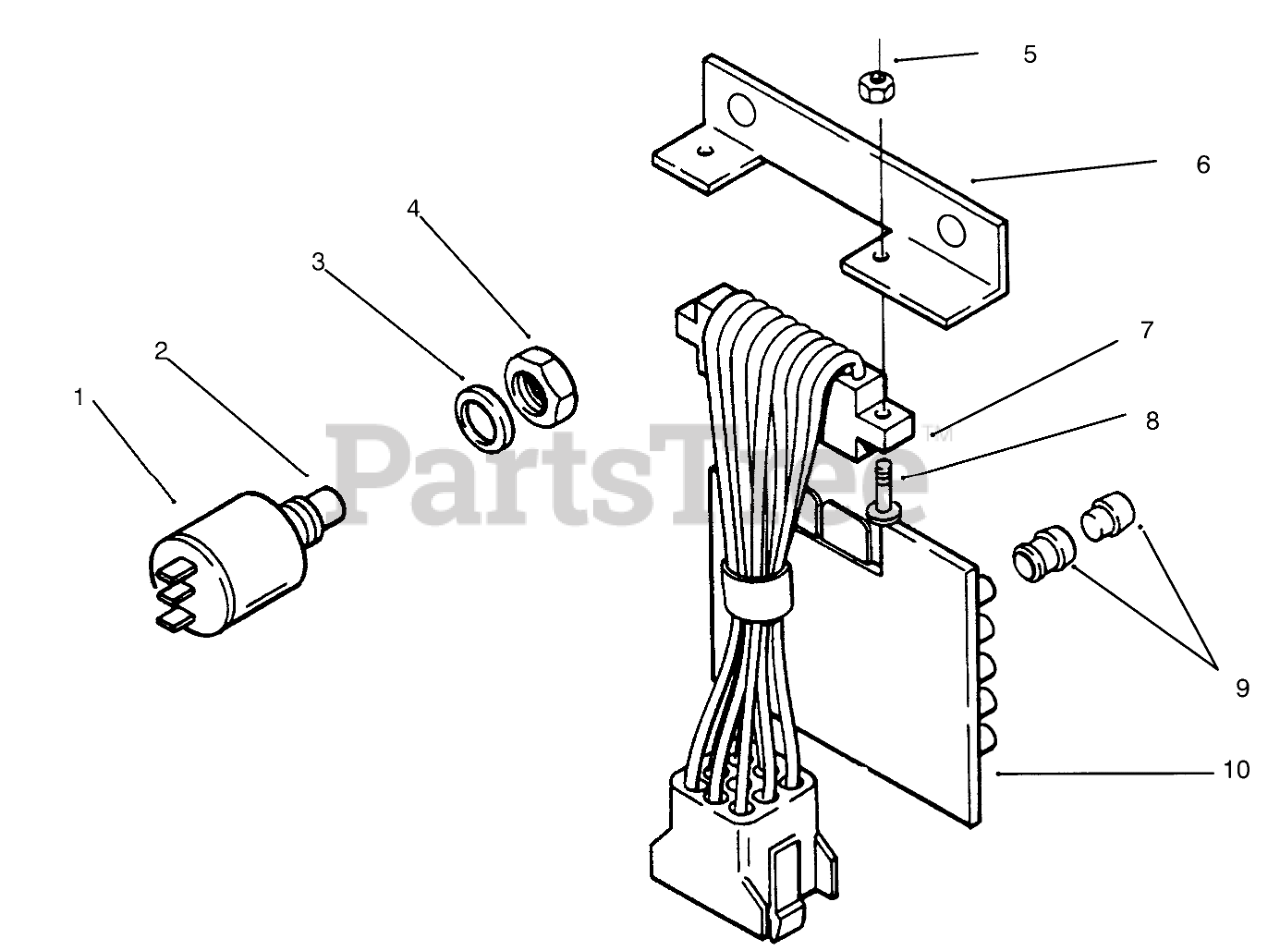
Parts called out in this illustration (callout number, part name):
1	SWITCH-PUSH BUTTON
2	Switch-Button (Incl. Ref. #2-4)
3	Washer
4	NUT F/W 116796
5	NUT HEX 4-40 ELAST
6	BRACKET
7	P.C.-BOARD HARNESS
8	Screw
9	ASSY LENS & BUSHING
10	Board-Pc
